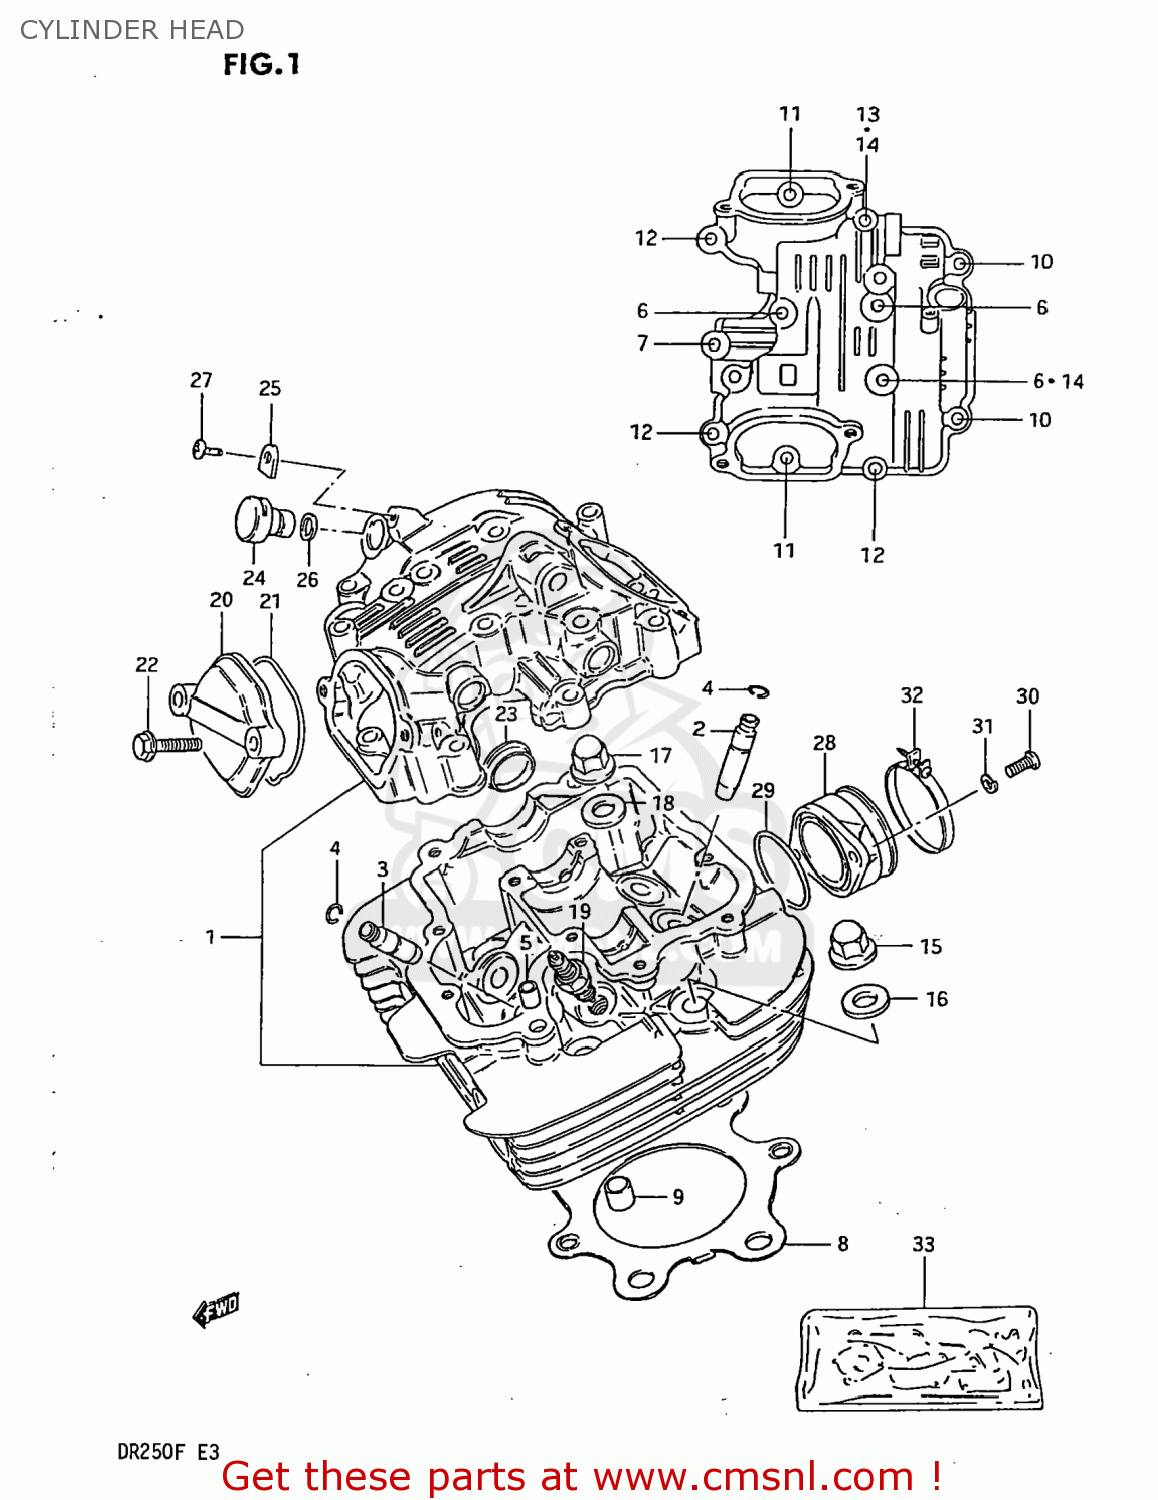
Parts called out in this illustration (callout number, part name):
1	HEAD,CYLINDER
2	GUIDE,INTAKE VALVE
3	GUIDE,VALVE
4	RING,SNAP
5	PIN(6.2X8X11)
6	BOLT ,6X60
7	BOLT 6X30
8	GASKET,CYLINDER HEAD (NAS)
9	PIN
10	BOLT
11	BOLT 6X30
12	BOLT (6X45)
13	BOLT ,6X60
14	WASHER
15	NUT
16	WASHER (10.5X22X2.3)
17	NUT
18	GASKET(10.5X22X2) (NAS)
19	SPARK PLUG D8EA
20	CAP,INSPECTION
21	O RING(D:2.4,ID:23)
22	BOLT
23	PLUG(OD:30)
24	PLUG,TACH GEAR SLEEVE HOLE
25	PLATE,TACH DRIVE GEAR SLEEVE
26	SEAL,TACHOMETER DRIVEN
27	SCREW(5X12)
28	PIPE,INTAKE
29	O-RING (D:2.4 ID:39.7)
30	SCREW
31	LOCK WASHER
32	CLAMP
33	GASKET SET (MCA)
